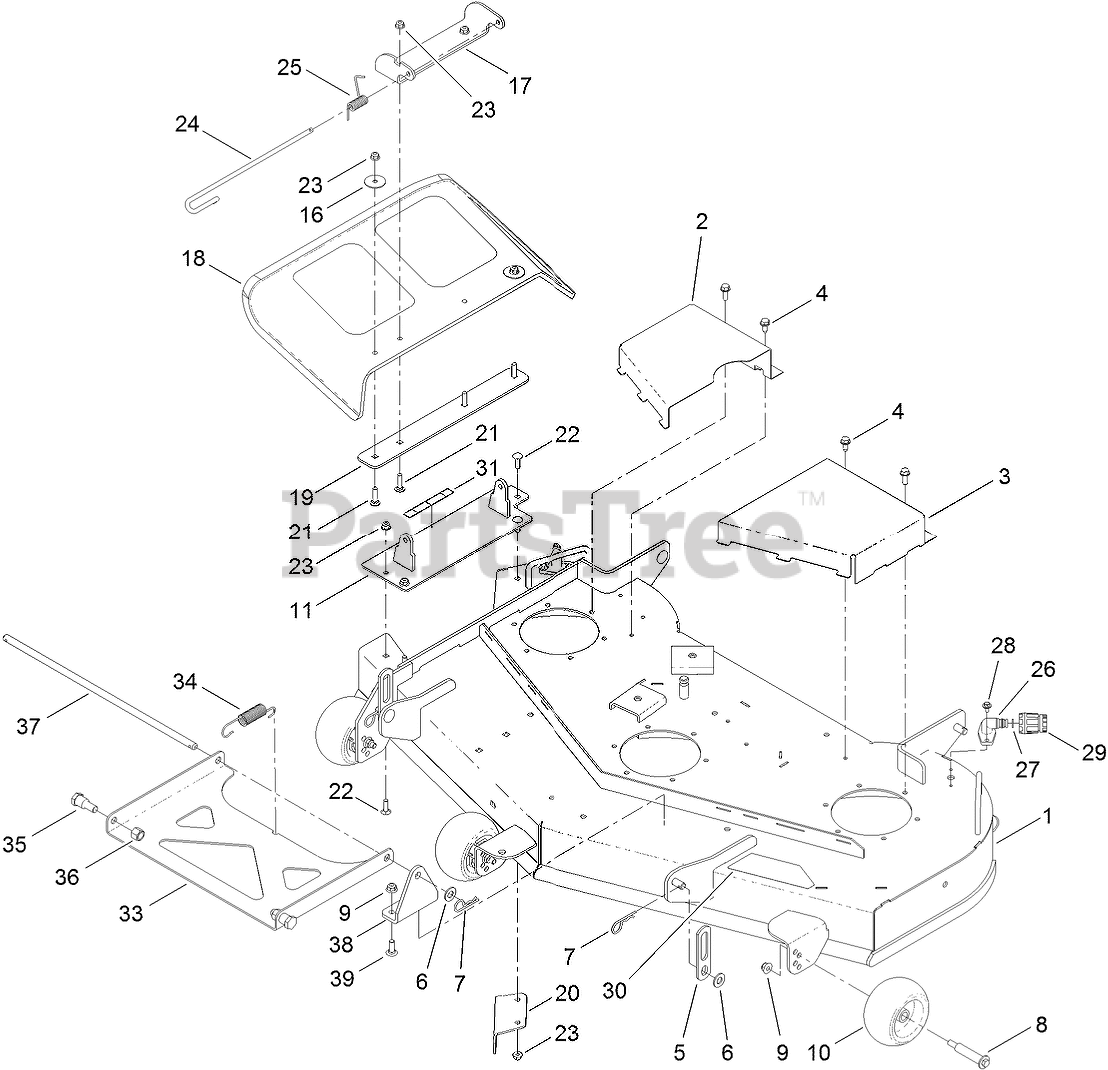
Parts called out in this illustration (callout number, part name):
1	48 INCH DECK AND DECAL ASM
2	COVER-BELT, RH
3	COVER-BELT, LH
4	SCREW-HWHTF
5	LINK-LIFT
6	WASHER-FLAT
7	PIN-COTTER
8	BOLT-SHOULDER
9	NUT-HF, NI
10	ROLLER-SCALP, ANTI
16	WASHER-FLAT
17	BRACKET-DEFLECTOR, UPPER
18	DEFLECTOR
19	PLATE-DEFLECTOR
20	BAFFLE-CUTOFF
21	SCREW-CARR
22	SCREW-CARR
23	NUT-HF, NI
24	PIN-CHUTE
25	SPRING-TORSION
26	FITTING-WASHOUT
27	O-RING
28	SCREW-HHFTF
29	CONNECTOR-HOSE
30	DECAL-DECK
31	DECAL-DANGER
33	PAN-PIVOT, DECK
34	SPRING-EXTENSION
35	BOLT-SHOULDER, HH
36	NUT-LOCK, NI
37	ROD-DECK, PIVOT
38	BRACKET-PIVOT, FRONT
39	SCREW-CARR
